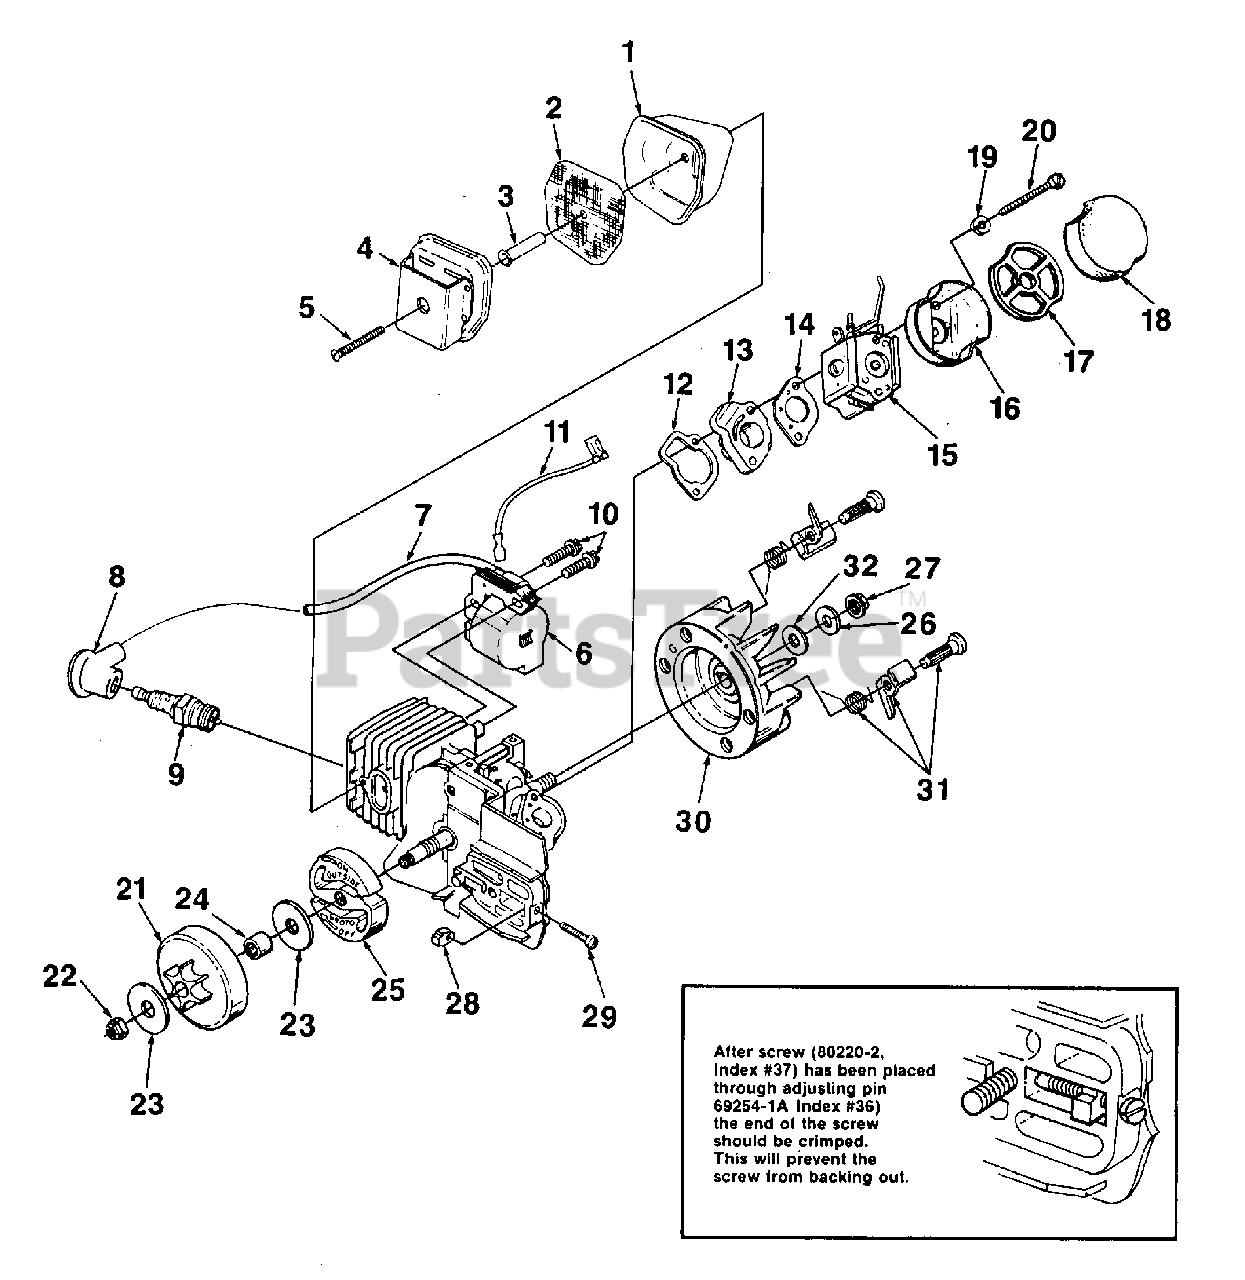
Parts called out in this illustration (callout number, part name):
1	BODY- Muffler
2	SCREEN- Spark arrestor
3	SPACER- Muffler
4	CAP- Muffler (w/shield)
6	MODULE- Ignition (solid state)
7	LEAD- High tension
8	TERMINAL- Spark plug
9	SPARK PLUG (Champion DJ7Y)
10	SCREW- Hex w/washer (8-32 x 3/4)
11	LEAD- Ground
12	GASKET- Intake manifold
13	MANIFOLD- Intake
14	GASKET- Carburetor
15	CARBURETOR- (HDC-65) Walbro
16	CUP- Air filter
17	RETAINER- Air filter
18	FILTER- Air
19	WASHER- Lock
20	SCREW- Hex hd. (10-32 x 2 1/4)
21	SPROCKET & DRUM
22	NUT- Locking (6/16-24)
23	WASHER- Thrust
24	BEARING- Needle
25	CLUTCH (S)
26	WASHER- Lock
27	NUT- Rotor (5/16-24)
28	PIN- Adjusting (see insert)
29	SCREW- Adjusting (Fil. hd. 8-32 x 1) (see insert)
30	ROTOR & STARTER PAWL (Phelon)
31	KIT- Starter pawl
32	WASHER- Flat
